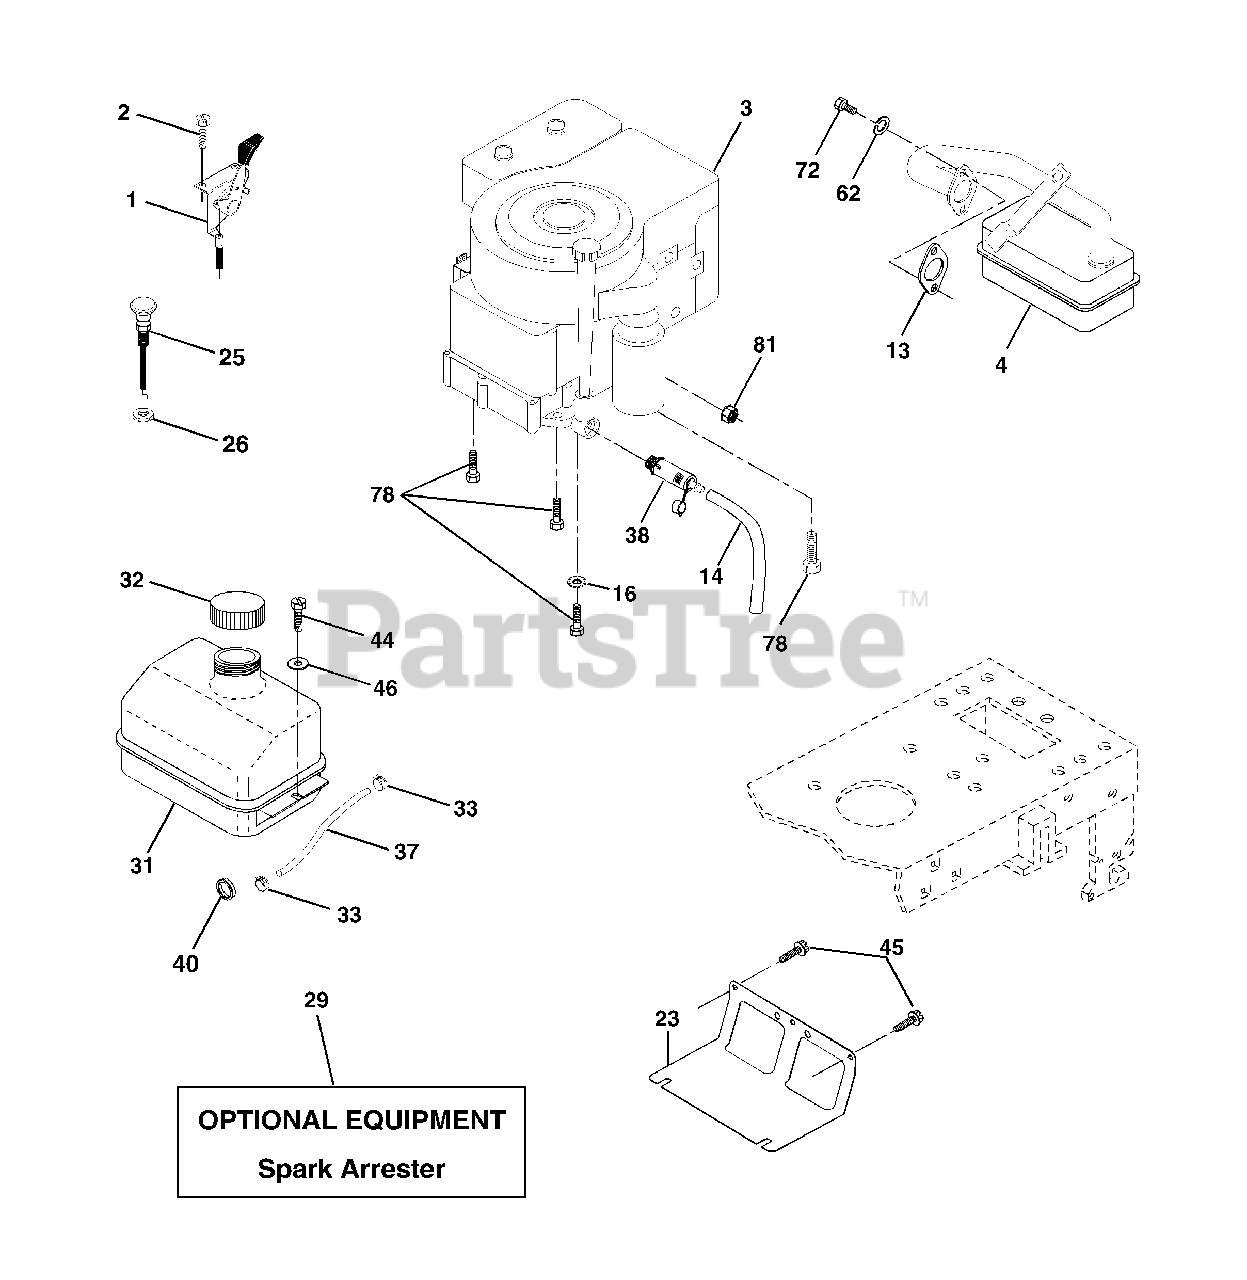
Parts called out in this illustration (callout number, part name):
1	Control Th/ch Flag
2	Screw Hex Thd Cut 1/4-20 x 1/2
4	Muffler Exhaust B&S
13	Gasket Eng 1 313 Id Tin Plated
14	Plug Drain Oil Easy
16	Washer Lock Ext Tooth 3/8
23	Shield BRN/DBR Guard
29	Kit Spark Arrestor (Flat Scrn)
31	Tank Fuel Front
32	Cap Asm Fuel
33	Clamp Hose
37	Line Fuel 20"
38	Tube Oil Drain Easy
40	Bushing Snap Nyl Blk Fuel Line
44	Screw Thdrol 1/4-20 x 3/4
45	Screw Hex Wsh Thdrol 3/8-16
46	Washer 9/32 X 7/8 X 16 Ga
62	Washer Lock Hvy Hlcl Spr
72	Screw Hexcap 5/16-18 x 3/4
78	Screw 3/8-16 x 1-1/4
81	Nut Keps Hex 1/4-20 Unc
